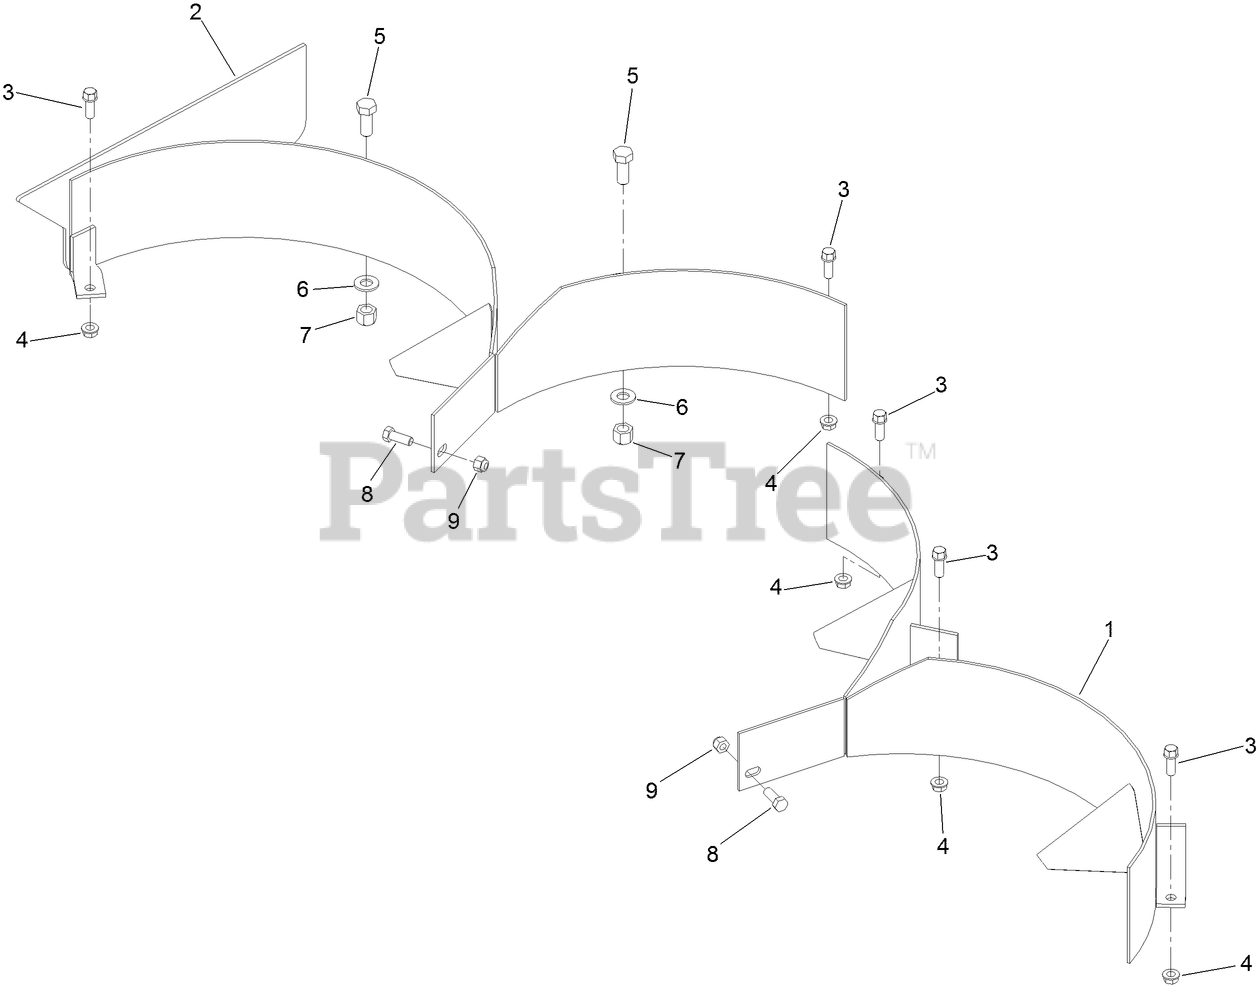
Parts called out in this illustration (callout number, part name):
1	BAFFLE-LH
2	BAFFLE-RH
4	NUT-HHF, WHIZ
5	SCREW-HH
6	WASHER-FLAT
7	NUT-LOCK, NI
8	SCREW-HH
9	NUT-LOCK, NI
